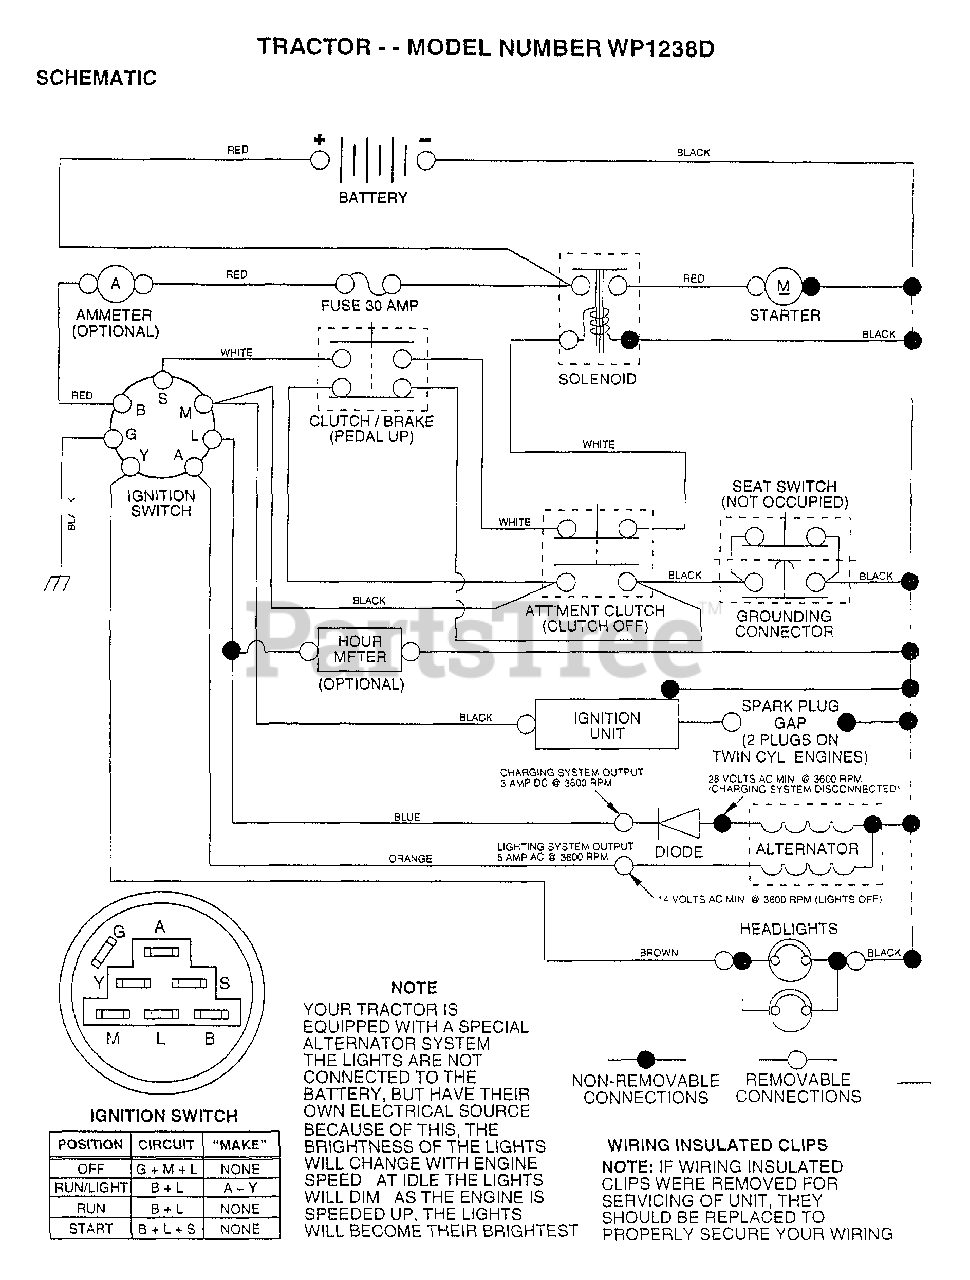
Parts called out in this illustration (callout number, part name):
2	BOLT LT
3	WASHER
4	LOCKWASHER
7	TUBE T
8	"CASE,BATTERY.MECH"
9	HOSE CLAMP T
15	FASTNER.SNAP-IN
16	SWITCH INTERLOCK
20	NUT
21	"HARNESS,LIGHT SOC"
22	HEADLAMP BULB
24	"CABLE T, BATTERY"
25	CABLE.BTRY.6GA.RD
26	FUSE HYT
28	CABLE T
29	SWITCH SEAT
30	SWITCH IGN 4POS
31	NUT IGNITION
32	COVER KEY SWITCH
33	KEY
40	HARNESS-IGNITION
41	BOLT HXHD FIN
44	NUT HXKEP 1/4X20
48	ADAPTER AMMETER
52	PROTECTION LOOP
70	HARNESS ENG DUAL
